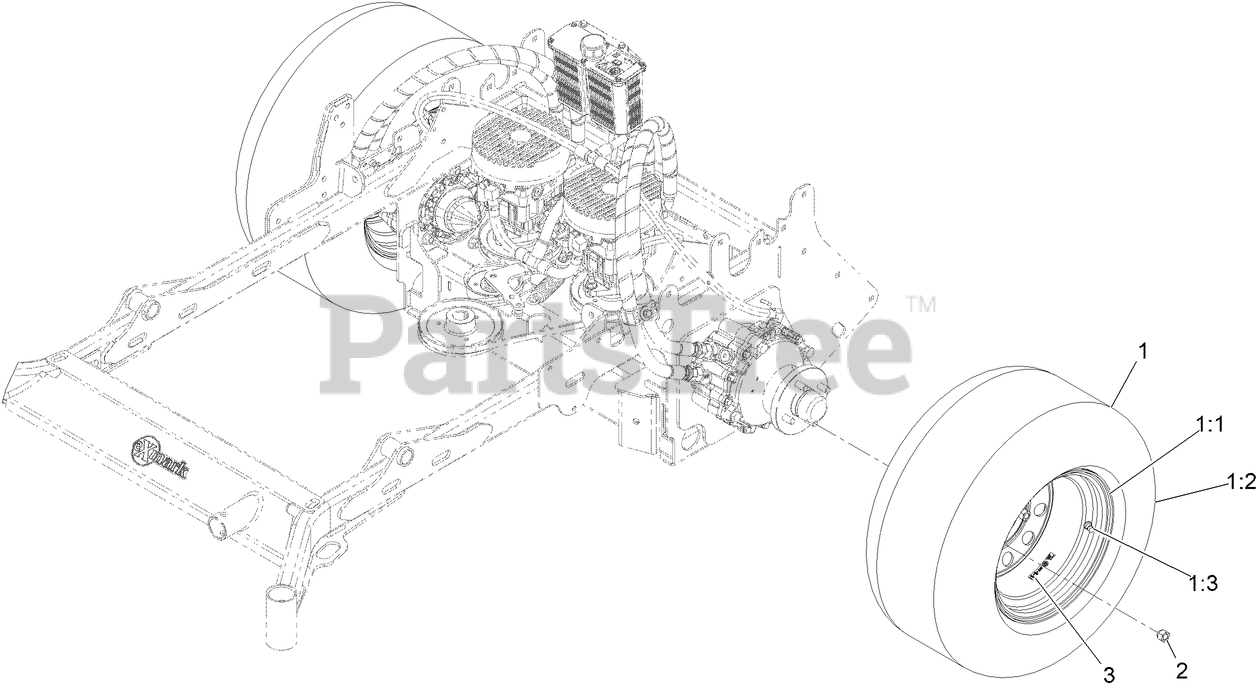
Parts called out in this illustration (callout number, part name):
1	ASM-24X12-12 WHEEL&TIRE
1:1	TIRE-24X12-12
1:3	VALVE
2	NUT-LUG
3	DECAL-TORQUE,WHEEL
